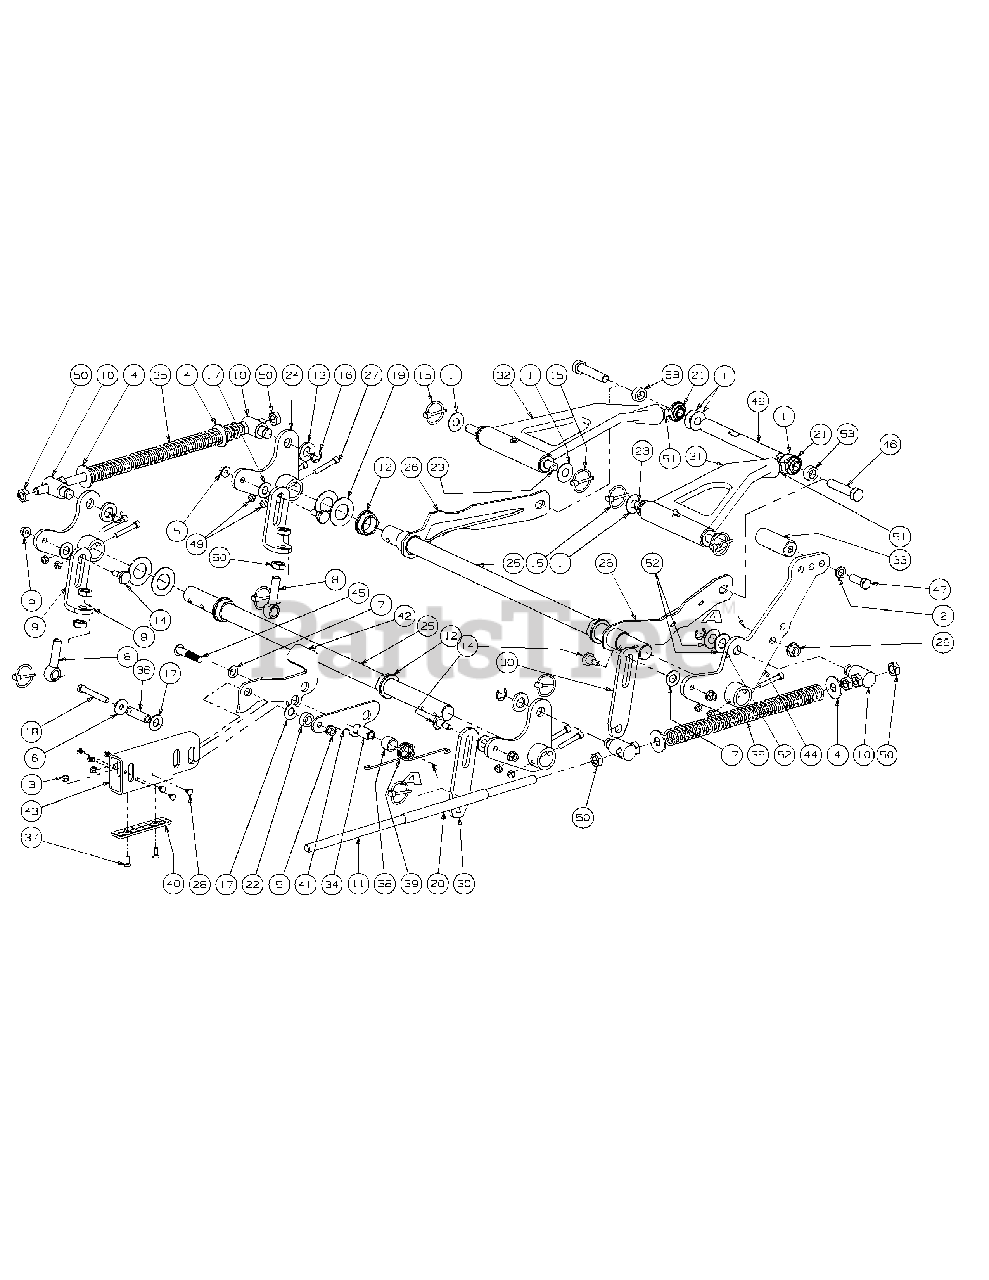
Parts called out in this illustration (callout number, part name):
1	Washer, 1.5 x .655 x .055
2	Lock Washer, 1/2
3	Lock Nut w/Nylon Insert
4	Flat Washer, 5/8
5	Hex Nut, Flange Lock, 3/8-16
6	Flat Washer, 1.25 x .411 x .100
7	Flat Washer, .536 ID x .930 OD x .05
8	Eye Bolt, 5/8ID
9	Eye Bolt, 5/8 ID
10	Ferule Lift
11	Lift Connector Rod
12	Hex Flange Bearing, 1.25 ID
13	Spacer, .812 ID x .268 Lg.
14	Shoulder Screw, 0.625 OD x .437 Lg.
15	Linch Pin, 3/16 Dia.
16	E Clip, 3/4 Dia.
17	Nylon Flat Washer, 5/8
18	HHCS, 3/8-16, 3.00
19	Flat Washer, 1.25 ID
20	Hose, 5/8 ID 13/16 OD, 8" LG
21	Rod End, Male
22	Spacer, .630 ID x 1.06 OD x .440
23	Deck Lift Link Rod
24	Bellecrank Weldment Assembly
25	Deck Lift Shaft
26	Front Frame Strut Assembly
27	Socket Head CapScrew, 5/16-18 x 2
28	Rivet, 1/4 x 5/8
29	Nut, 1/2-13, FlangeLock
31	Bearing Lift Brace Assembly, Left Hand
31	Grease Fittting
32	Bearing Lift Brace Assembly, Right Hand
32	Grease Fitting
33	Deck Lift Foot Pedal
34	Spacer, .51 ID x .75 OD x 1.240
35	Lift Compression Spring
36	Spacer, .375 ID x .625 OD x 1.53
37	Flat Head CapScrew, 1/4-20 x .75
38	Spacer, .76 ID x 1.0 OD x .75
39	Torsion Spring, .120 Wire x 1.32 OD
40	Lift Wear Plate
42	Lift Link Bracket
43	Lift Tube, 3.0 x 1.5, 1" Height
44	Deck Lift Foot Pedal Weldment
45	Socket Head CapScrew, 1/2-13 x 2.50
46	HHCS:5/8-11 x 3.00
47	Hex Cap Screw, 1/2-13 x 1.50
48	Front Lift Link Shaft, Threaded
49	Nut, 5/16-18, Nylock
50	Jam Nut, 5/8-11
51	Jam Nut, 5/8-18
52	Washer, .76 x 1.49 x .06
53	Spacer, .632 x .877 x .548
